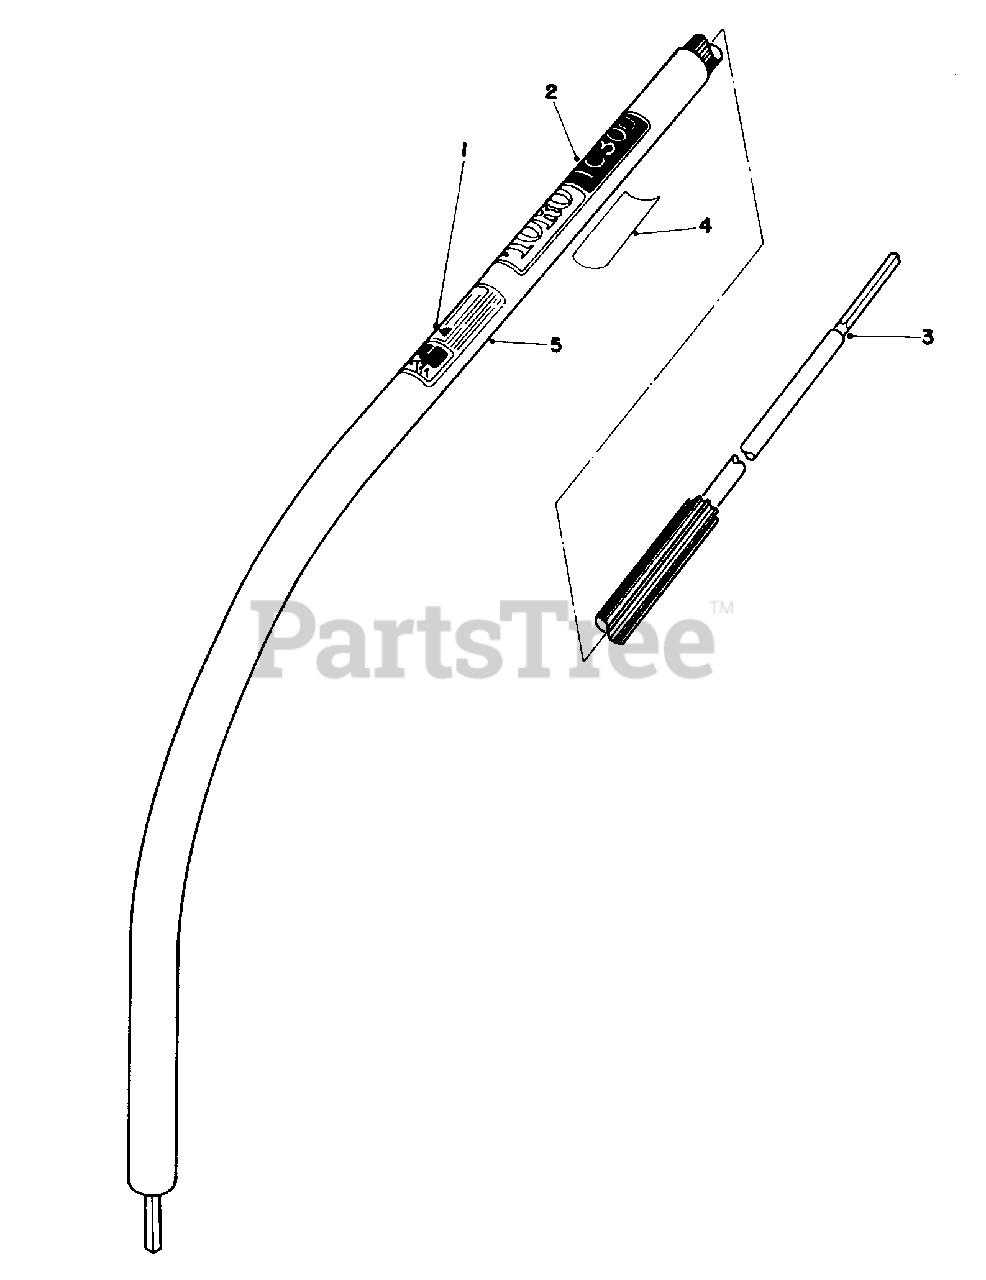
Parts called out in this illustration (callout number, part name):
1	Decal-Caution
2	Decal-Toro TC 300
3	Shaft-Flex
4	Replacenfnl Serial Plate
5	Tube-Lower Shaft Housing (Incl. Ref. #2)
